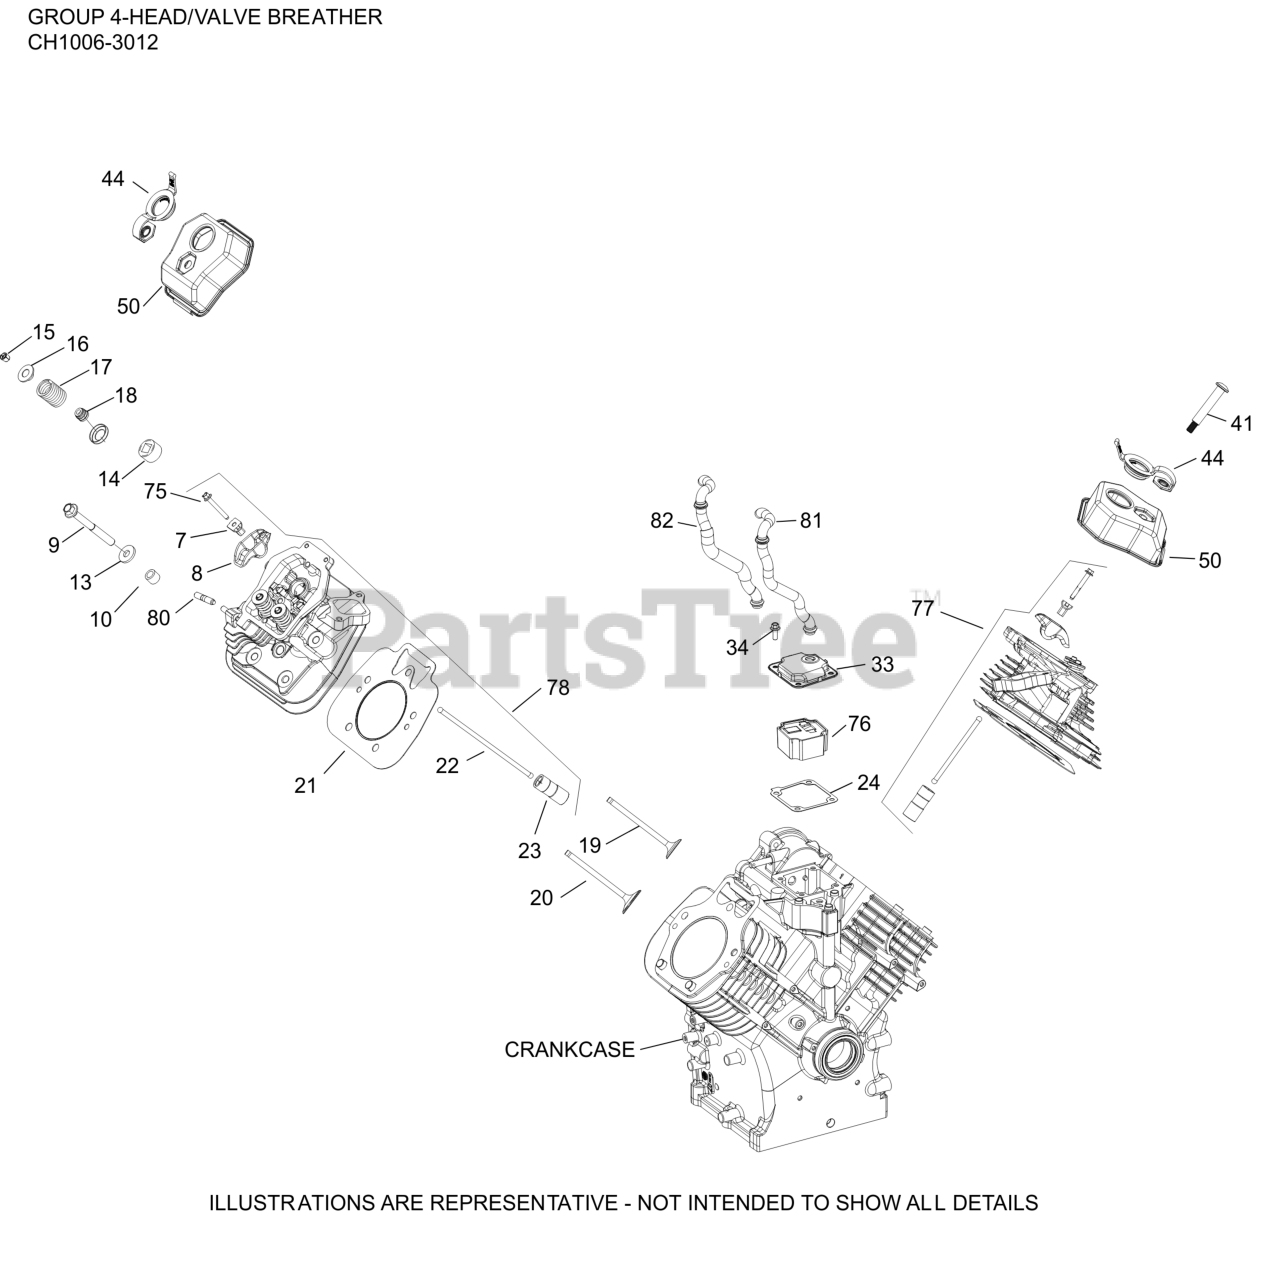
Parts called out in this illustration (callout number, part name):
7	PIVOT, ROCKER ARM
8	ARM, ROCKER
9	SCREW, FLG M10X1.5X90
13	WASHER, FLAT 13/32"
14	PLUG, PIPE 3/4 NPTF SQUARE
15	KIT, RETAINER
16	CAP, VALVE SPRING
17	SPRING, VALVE
18	SEAL, VALVE BAND
19	VALVE, EXHAUST (NITRIDE)
20	VALVE, INTAKE (NITRIDE)
21	KIT, CYLINDER HEAD GASKET
22	ROD, PUSH
23	LIFTER, VALVE HYDRAULIC-USE 25 351 11-S
24	GASKET, BREATHER
33	KIT, BREATHER ASSEMBLY
34	SCREW, THREAD FORMING
41	SCREW, SHOULDER
44	GROMMET, OIL FILL
50	KIT, VALVE COVER
75	SCREW, HEX FLANGE
76	FILTER, BREATHER
77	KIT, #1 CYLINDER HEAD COMPLETE
78	KIT, #2 CYLINDER HEAD COMPLETE
80	STUD, METRIC EXHAUST
81	HOSE, BREATHER
82	BREATHER ASSEMBLY, HEATED
